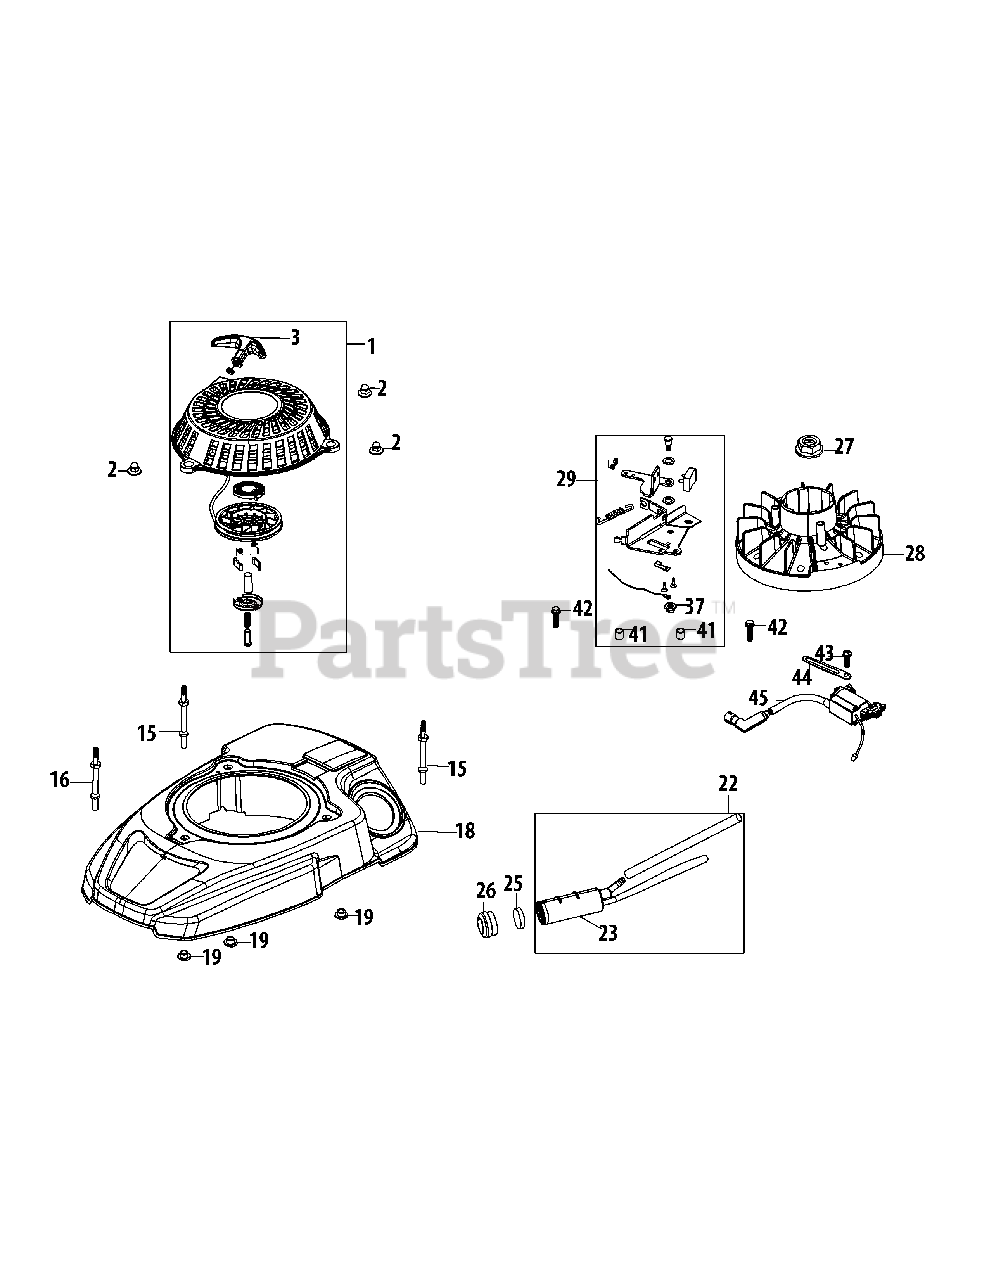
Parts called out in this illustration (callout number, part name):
1	Starter Recoil Assembly
2	Starter Acorn Nut
3	Starter Handle
15	Starter/Shroud Rear Stud M6×78.5
16	Starter/Shroud Front Stud M6×74
18	Engine Shroud
19	Engine Shroud Spacer
22	Carbon Canister Assembly
23	Carbon Canister
25	Carbon Canister Filter
26	Carbon Canister Filter Cap
27	Flywheel Nut M14
28	Flywheel
29	Brake Assembly
37	Brake Arm Nut
41	Brake Spacer
42	Bolt M6X35 Af Base/Brake/Dipstick
43	Bolt M6×20 Ignition Coil
44	Flexible Clamp, Ignition Coil
45	Ignition Coil Assembly
